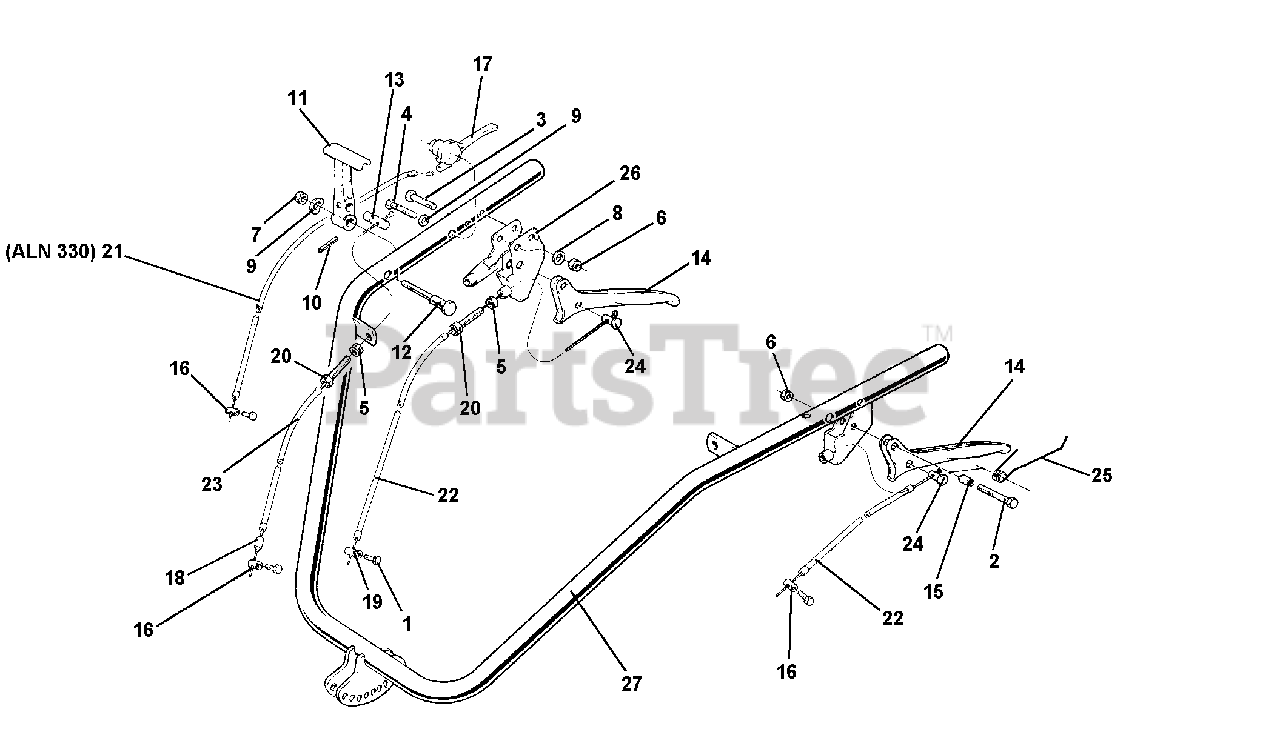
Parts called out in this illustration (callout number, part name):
1	SCREW TE M6 X 14
2	SCREW M6 X 25
3	SCREW M6 X 40
4	SCREW TE M8 X 40
6	NUT, SELF LOCKING M6
7	NUT, SELF LOCKING M8
8	WASHER, LOCK 6.4
9	WASHER, LOCK 8.4
10	PIN, LOCKING 4 X 20
11	LEVER DIFFERENTIAL LOCKING
13	DRILLED PIN
15	LEVER SPACER
16	CLAMP, CABLE
17	LEVER, ACCELERATOR
18	END, SHEATH
19	PIN, CABLE CLAMP
20	SCREW, ADJUSTING M8
21	WIRE, SHEQATH 1850 GAS
22	SHEATH CABLE
23	SHEATH CABLE
25	LEVER SPRING
26	COUPLING FOR DOUBLE LEVER
